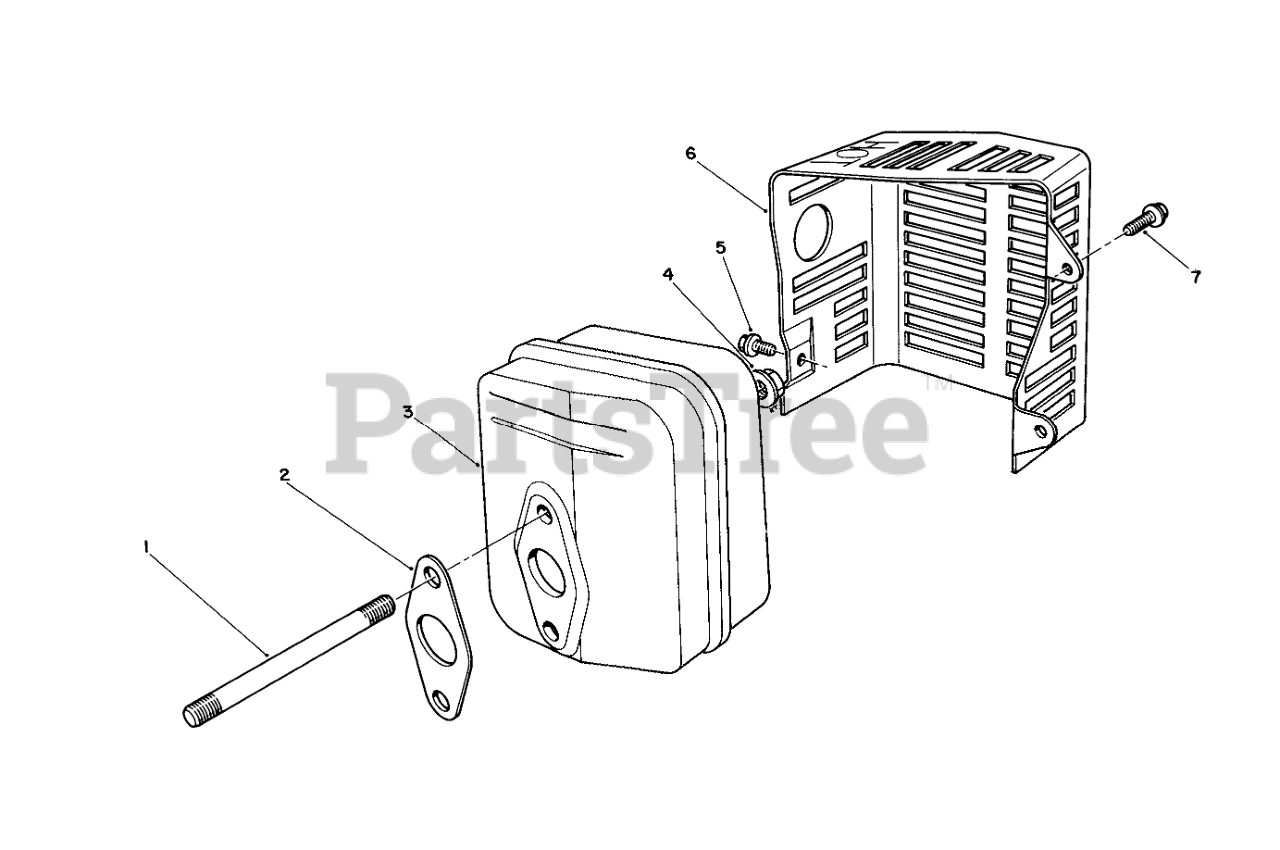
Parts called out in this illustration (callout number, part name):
2	GASKET
3	MUFFLER
5	SCREW
6	COVER
